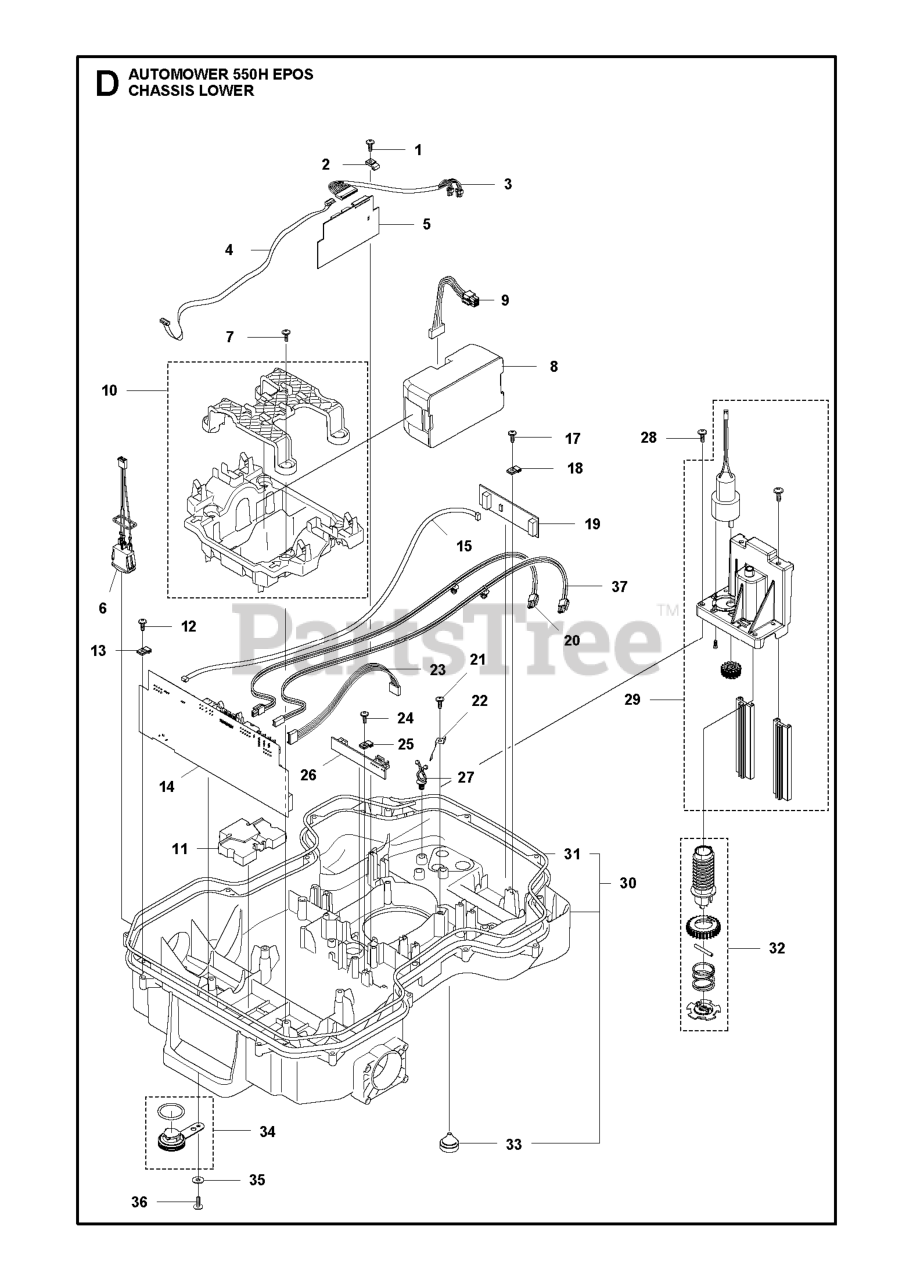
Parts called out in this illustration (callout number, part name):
1	SCREW 14MM
2	CLAMP PCB
3	Wires
5	PRINTED CIRCUIT ASSY ULTRASONI
6	LOOM ON/ OFF
7	SCREW ITXPANT
8	BATTERY
9	WIRING ASSY BATTERY CABLE
10	HOLDER KIT BATTERY
11	WEIGHT 470G
12	SCREW 14MM
13	CLAMP PCB
14	PRINTED CIRCUIT ASSY PCBA MAIN
15	LOOM LOOP SENSOR
17	SCREW 14MM
18	CLAMP PCB
19	PRINTED CIRCUIT ASSY LOOP SENS
20	LOOM CHARGING LINK HIGH CHARGI
21	SCREW 14MM
22	SPRING GUIDE HEIGHT ADJUSTMENT
23	LOOM HEIGHT ADJUSTMENT
24	SCREW 14MM
25	CLAMP PCB
26	PRINTED CIRCUIT ASSY PCBA CUTT
27	HOLDER TWIST LOCK
28	SCREW 14MM
29	MOTOR ASSY HEIGHT MOTOR
30	CHASSIS KIT LOWER HI-CUT
31	SEALING STRIP
32	SCREW KIT
33	GROMMET M16
34	PLUG KIT
35	WASHER
36	SCREW ITXPANT
37	WIRING ASSY LED LIGHT EXTENSIO
